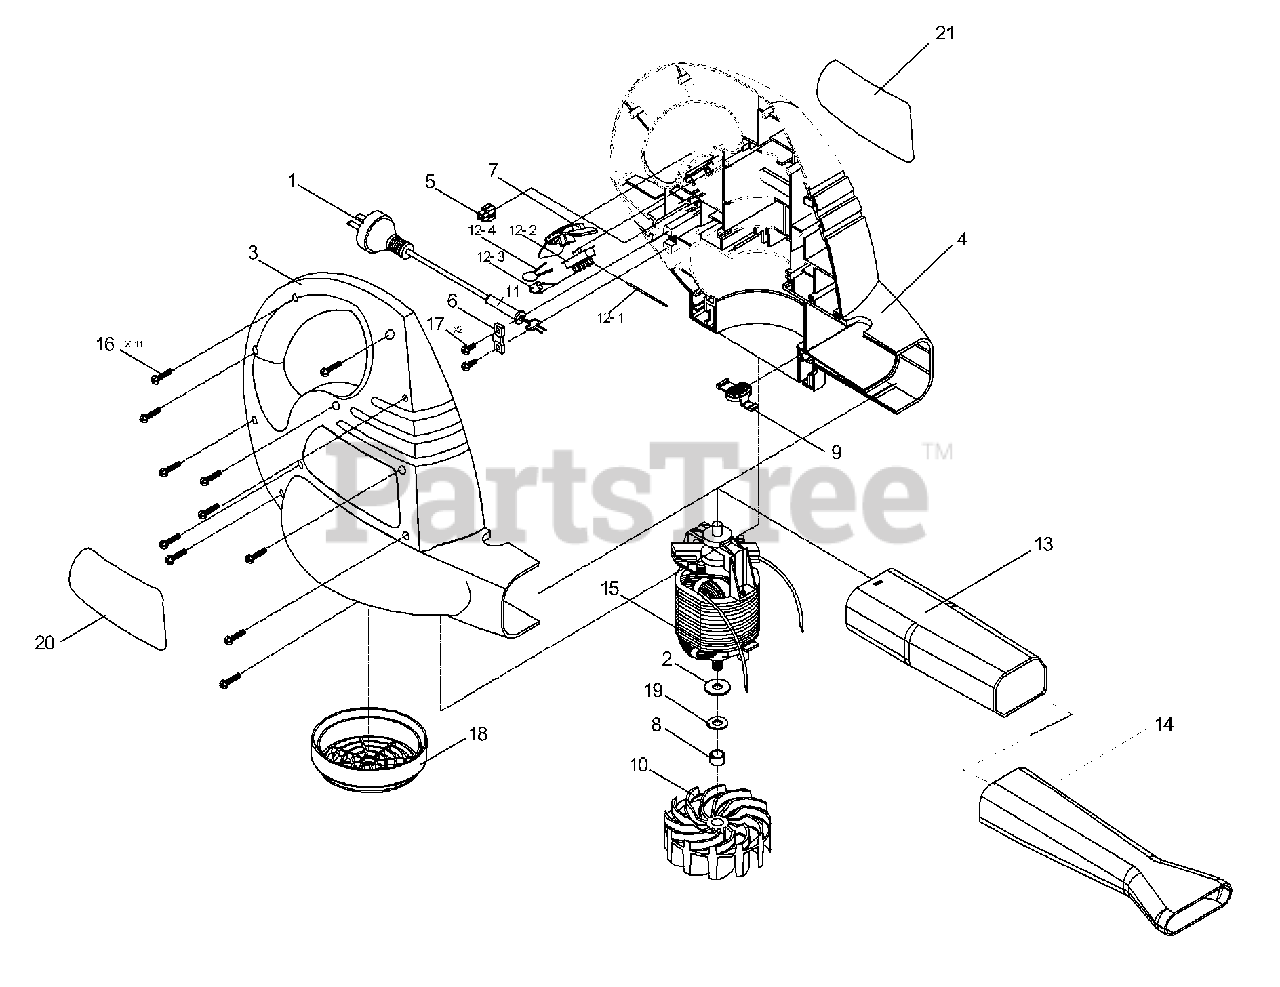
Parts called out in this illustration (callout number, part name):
1	POWER CORD
3	HOUSING (L)
4	HOUSING (R)
5	TERMINAL BLOCK
6	STRAIN RELIEF
8	SHAFT SLEEVE
11	CORD GUARD
12	SWITCH ASS'Y
18	SAFETY COVER
